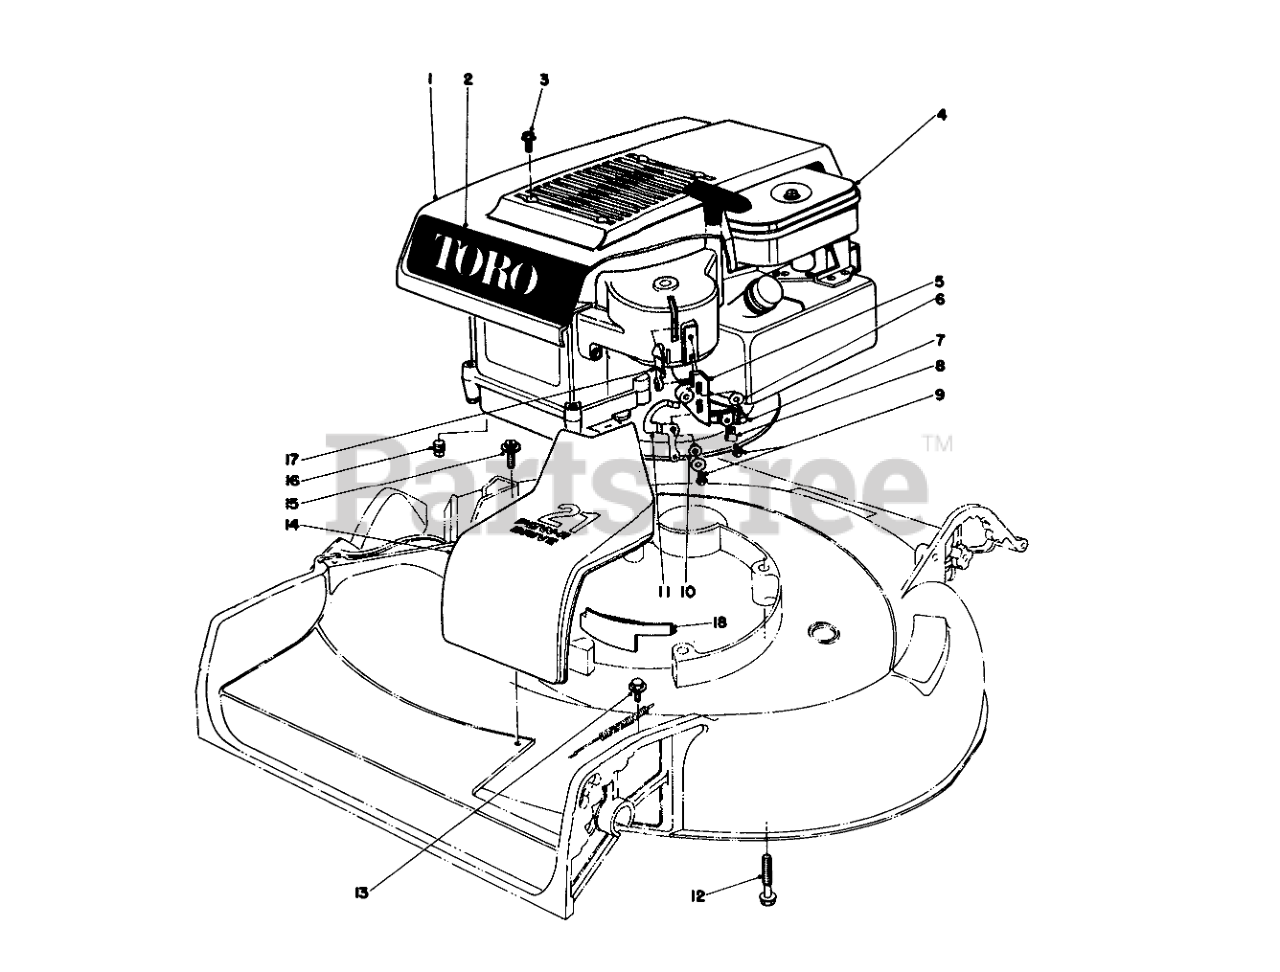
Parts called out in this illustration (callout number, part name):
1	SHROUD
2	Decal-Toro
3	8X1/2 SELF TAP SCREW
4	Engine
5	CABLE & PIVOT BLOCK
6	WASHER-FLAT
7	SCREW-SHWH
8	CLAMP
9	SCREW-HHFTF
10	BUSHING
11	CAM INTERLOCK
12	3/8-16 X 2-3/4 CAPSCR
13	SCREW-HWHTF
14	BELT DRIVE COVER
15	SCREW
16	PLUG-PIPE, SQH
17	INTERLOCK LEVER
18	HOUSING CAP
